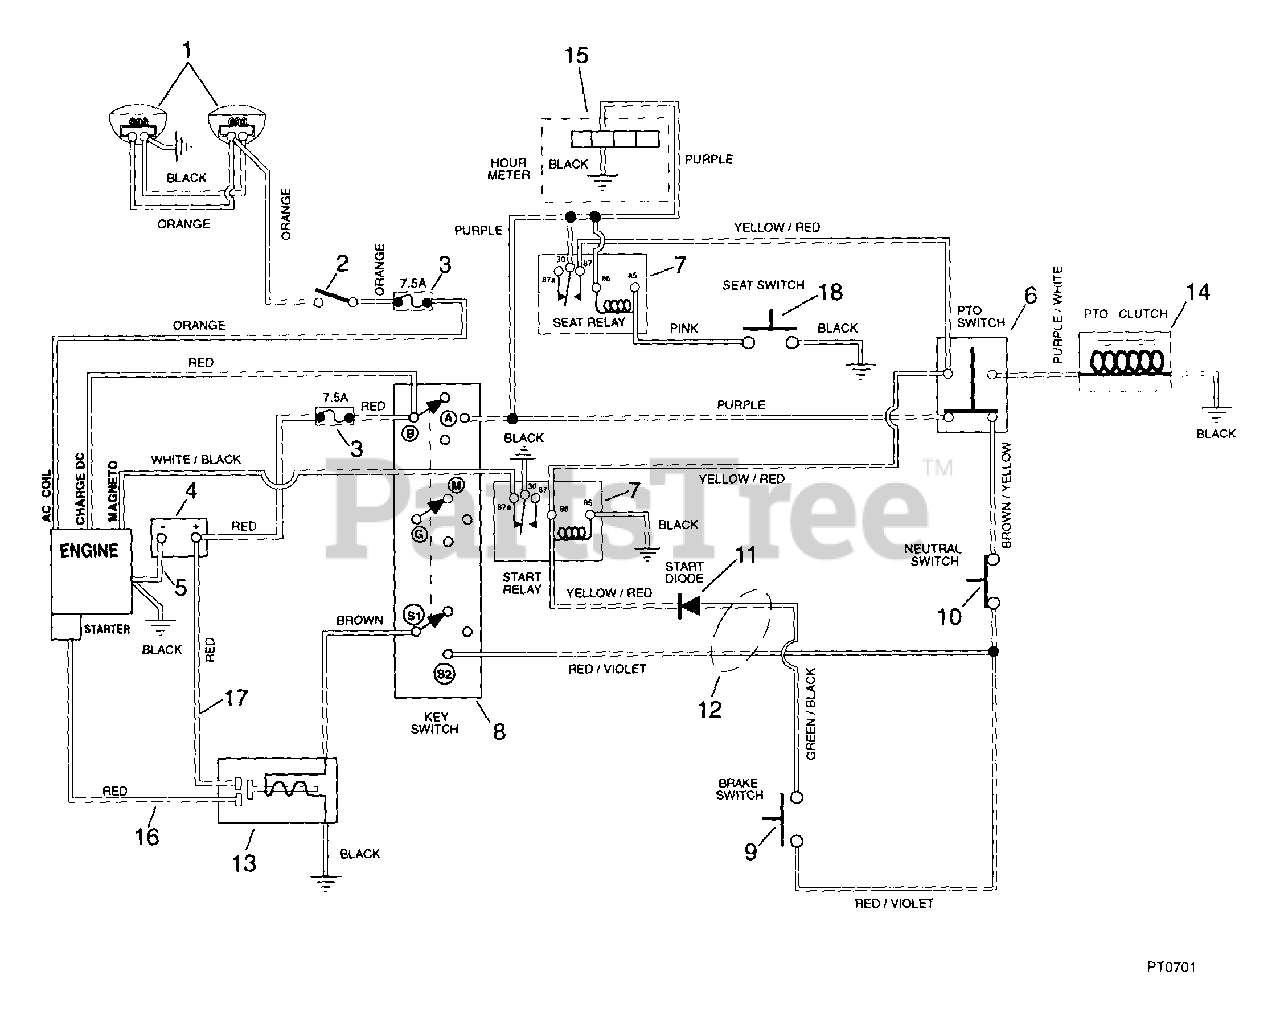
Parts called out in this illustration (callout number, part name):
1	HEADLIGHT- RH
2	SWITCH - LIGHT
3	7.5 AMP Fuse
4	BATTERY W/TUBE
5	GROUND CABLE .31X22.00X.31
6	PTO KNOB/ SWITCH ASSY
7	RELAY
8	KEY SWITCH
9	SWITCH- SINGLE POLE N.O.
10	SWITCH, NEUTRAL START N.C.
11	MOLDED DIODE PLUG 1 AMP
12	WIRE HARNESS - 1340G TEC
13	SOLENOID
14	ELECTRIC CLUTCH/BRAKE(1.8AMP)
15	HOURMETER KIT- SIERRA
16	START CABLE 22"
17	STARTER CABLE 6.75"
18	SWITCH- SEAT
